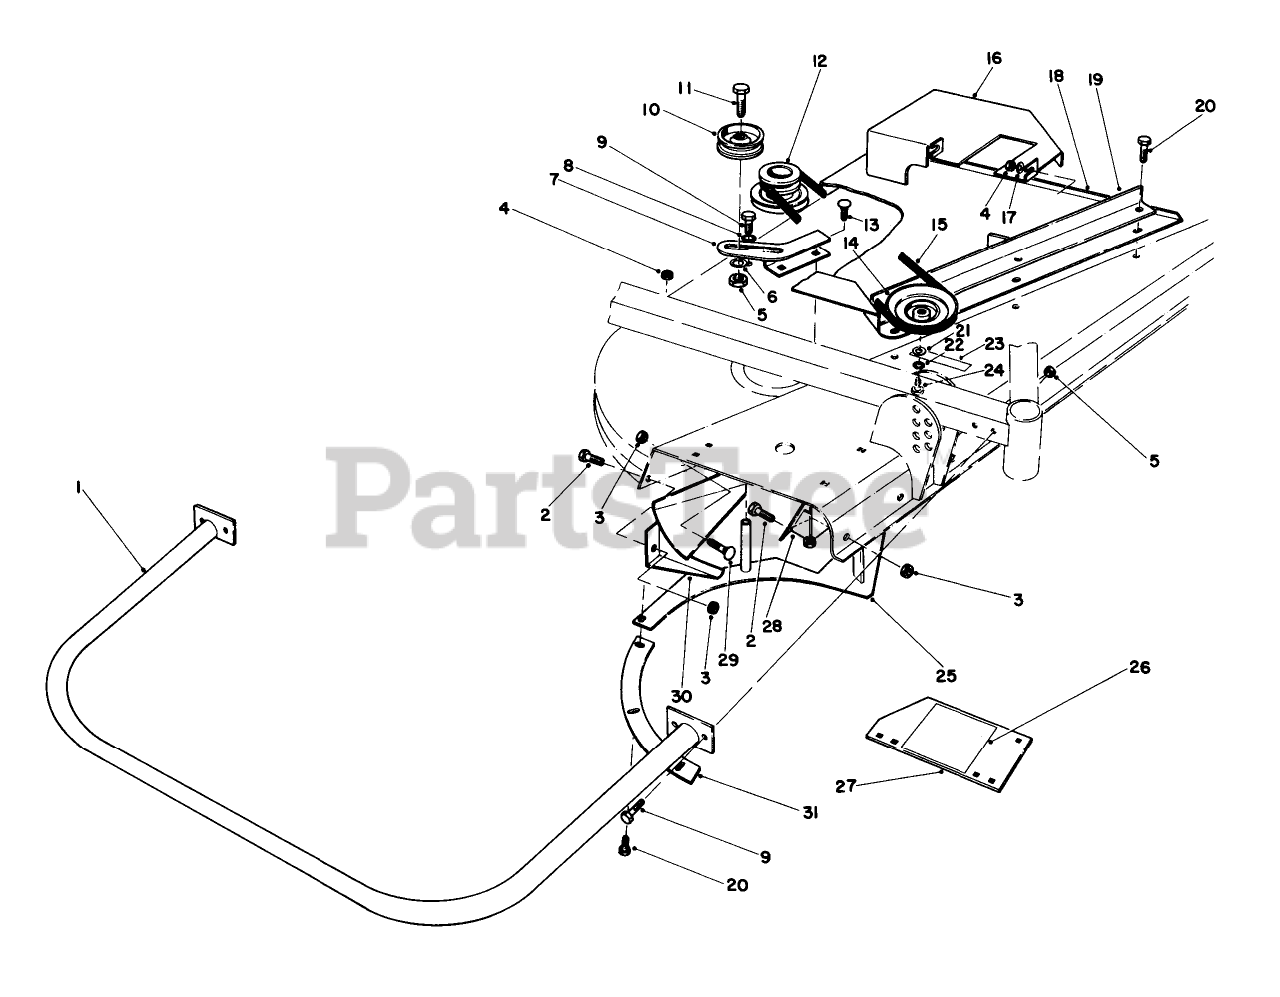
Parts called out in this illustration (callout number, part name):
1	Bumper
2	SCREW-HH
3	NUT-LOCK, CONE
4	NUT-LOCK, CONE
5	NUT-LOCK, CONE
6	WASHER-FLAT
7	IDLER BRKT R
8	WASHER-LOCK
9	SCREW-HH
10	IDLER PULLEY R
11	SCREW-HH
12	PULLEY WA RO
13	BOLT-CARR
14	PULLEY WA BO
15	V-BELT
16	Cover Blower Drive
17	WASHER-FLAT
18	Cover-Right
19	Spring Bracket
20	SCREW-HH
21	Washer
22	WASHER-LOCK
23	WARNING DECAL
24	1/4-20 X 5/8 CAPSCREW
25	Rear Shelf
26	Decal-Caution
27	Cover Plate (Incl. Ref. #26)
28	Front Deflector
29	BOLT-CARR
30	Deflector Rear
31	Shelf-RH
